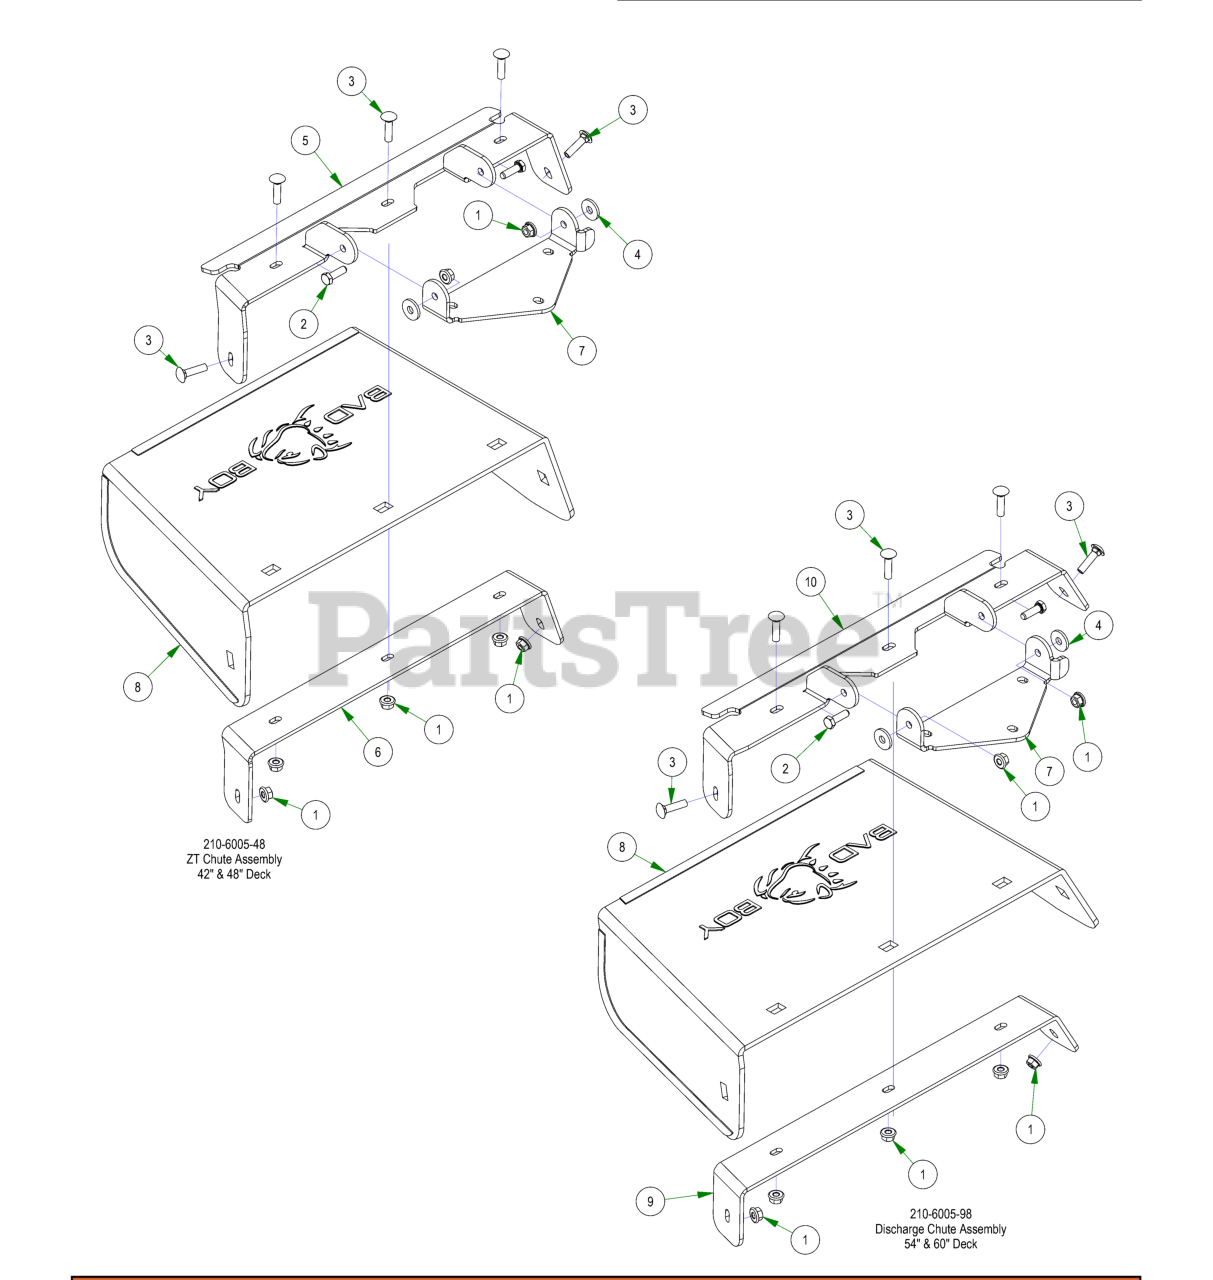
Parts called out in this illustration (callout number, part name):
1	5/16-18 NYLON INSERT FLANGE LOCKNUT ZINC
2	5/16-18 X 1 HEX CAP SCREW (GR.5) ZINC
3	5/16-18 X 1-1/4 CARRIAGE BOLT ZINC
4	.360 ID X .983 OD X .120 THICK FLAT WASHER NYLON
5	Discharge Upper Chute Bracket
6	Discharge Lower Chute Bracket
7	Discharge Chute Hanger (deck mounted)
8	Rubber Discharge Chute
9	60" Discharge Lower Bracket
10	60" Discharge Chute Upper Hanger
